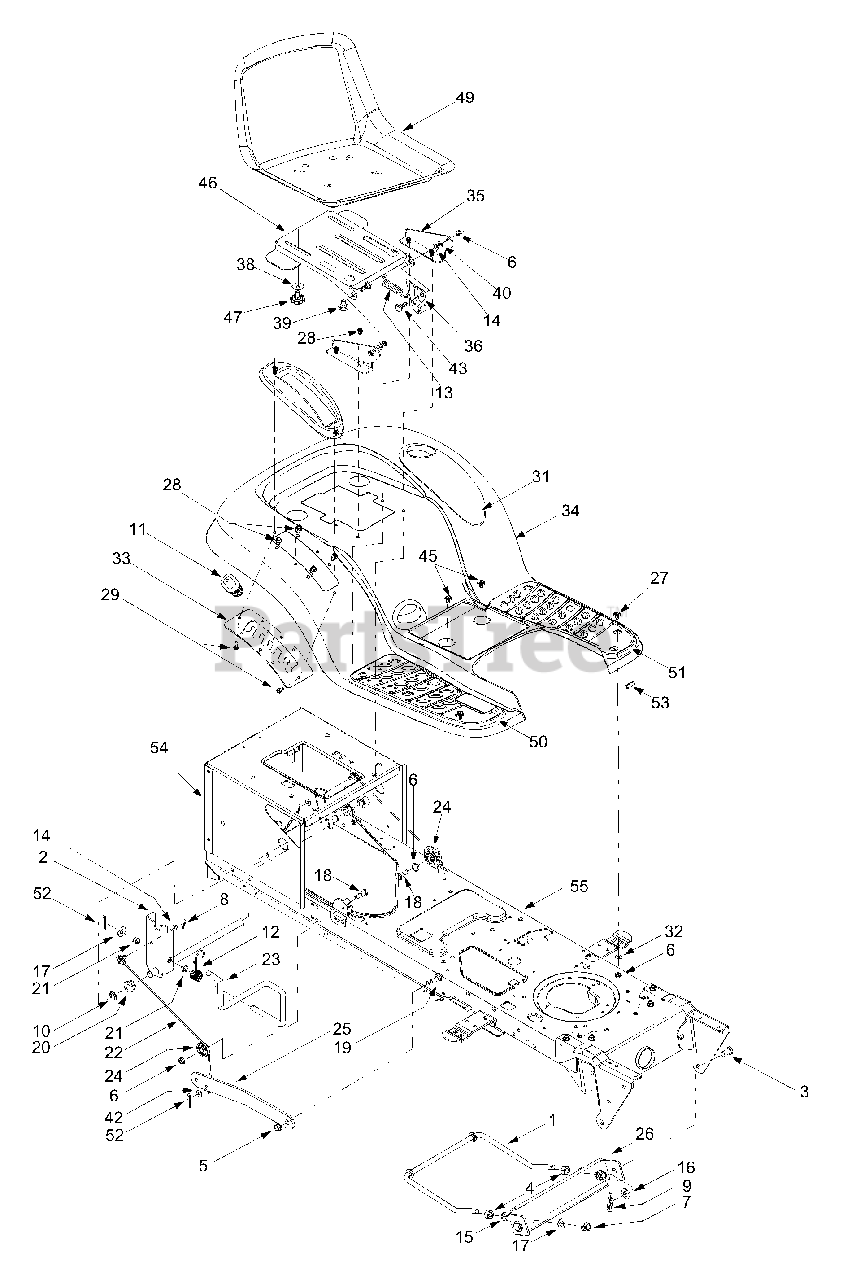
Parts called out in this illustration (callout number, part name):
1	Deck Stabilizer Rod
3	Clevis Pin, .5 x .78
4	Lock Nut, 1/2-13
5	Lock Nut, 3/8-16
6	Lock Nut, 5/16-18
7	Hex Nut, 1/2-13
8	Internal Cotter Pin
9	Internal Cotter Pin
12	Torsion Spring
13	Extension Spring, .872 x 3.4
14	Flat Washer, 5/16
15	Lock Washer, 1/2
16	Flat Washer, .31 x 1.062 x .134
17	Flat Washer, .51 x 1.12 x .06
18	Hex Cap Screw, 5/16-18 x .62
19	Shoulder Screw, 3/8-16
20	Hex Flange Bearing
21	Snap Flange Bearing
22	Lift Cable, 16.16
24	Roller Pulley
27	Carriage Bolt, 5/16 x .62
28	Self-Tapping Screw, 5/16-18 x .625
29	Self-Tapping Screw, 1/4-15 x .75
30	Lift Lever Cover
31	Cover w/ Cup Holder
32	Flat Washer, .349 x 1.0 x .063
36	Lift Bracket: Seat
37	Hex Flange Lock Nut, 1/4-20
38	Bell Washer
39	Shoulder Screw 3/8-16
41	Spring Washer, .265 x .562 x .025
42	Flat Washer, .344 x .62 x .03
43	Shoulder Screw
44	Shoulder Screw, .50 x .925, 3/8-16
45	Self-Tapping Screw 1/4-20 x 0.5"
47	Adjustment Knob: Seat
48	Seat Adjustment Selector
49	Medium Back Seat, Black
